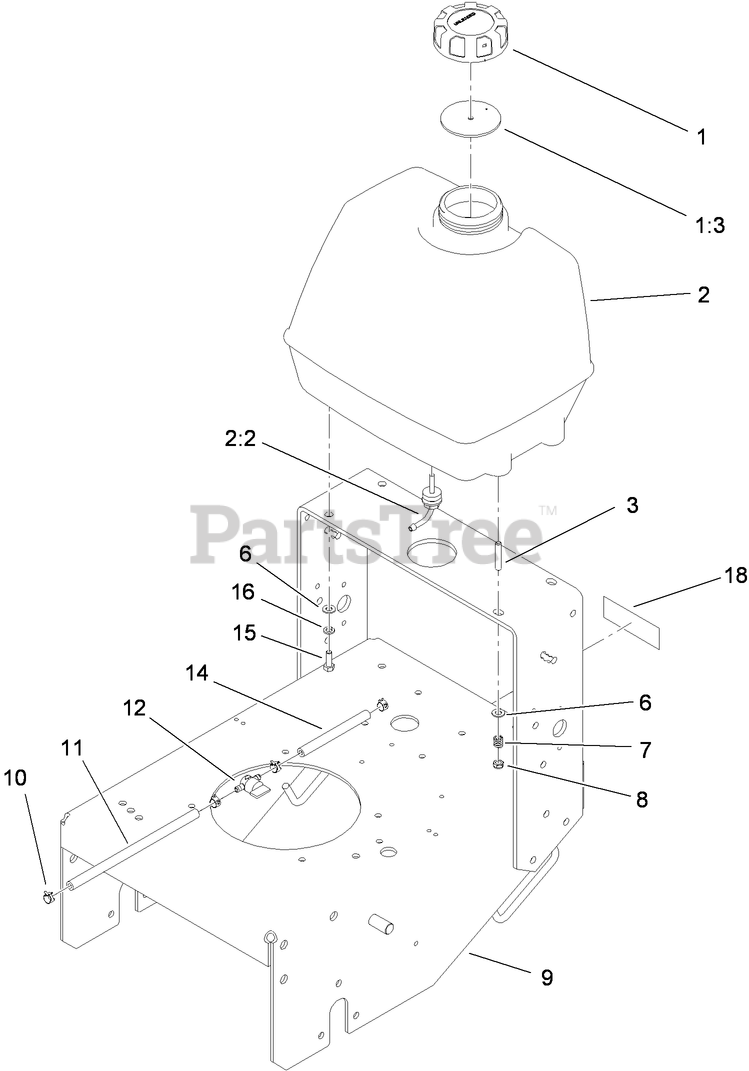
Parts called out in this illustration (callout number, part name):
1	GAS CAP ASM
1:3	GASKET-CAP, GAS
2	FUEL TANK ASM
2:2	FITTING-FUEL, BULKHEAD
3	STUD-THREADED
6	WASHER-PLAIN
7	SPRING-TANK, FUEL
8	NUT-LOCK, NI
9	GEAR FRAME ASM
10	CLAMP-HOSE
11	HOSE-FUEL
12	VALVE-FUEL
14	HOSE-FUEL
15	SCREW-HH
16	WASHER-LOCK
18	DECAL-CAUTION
